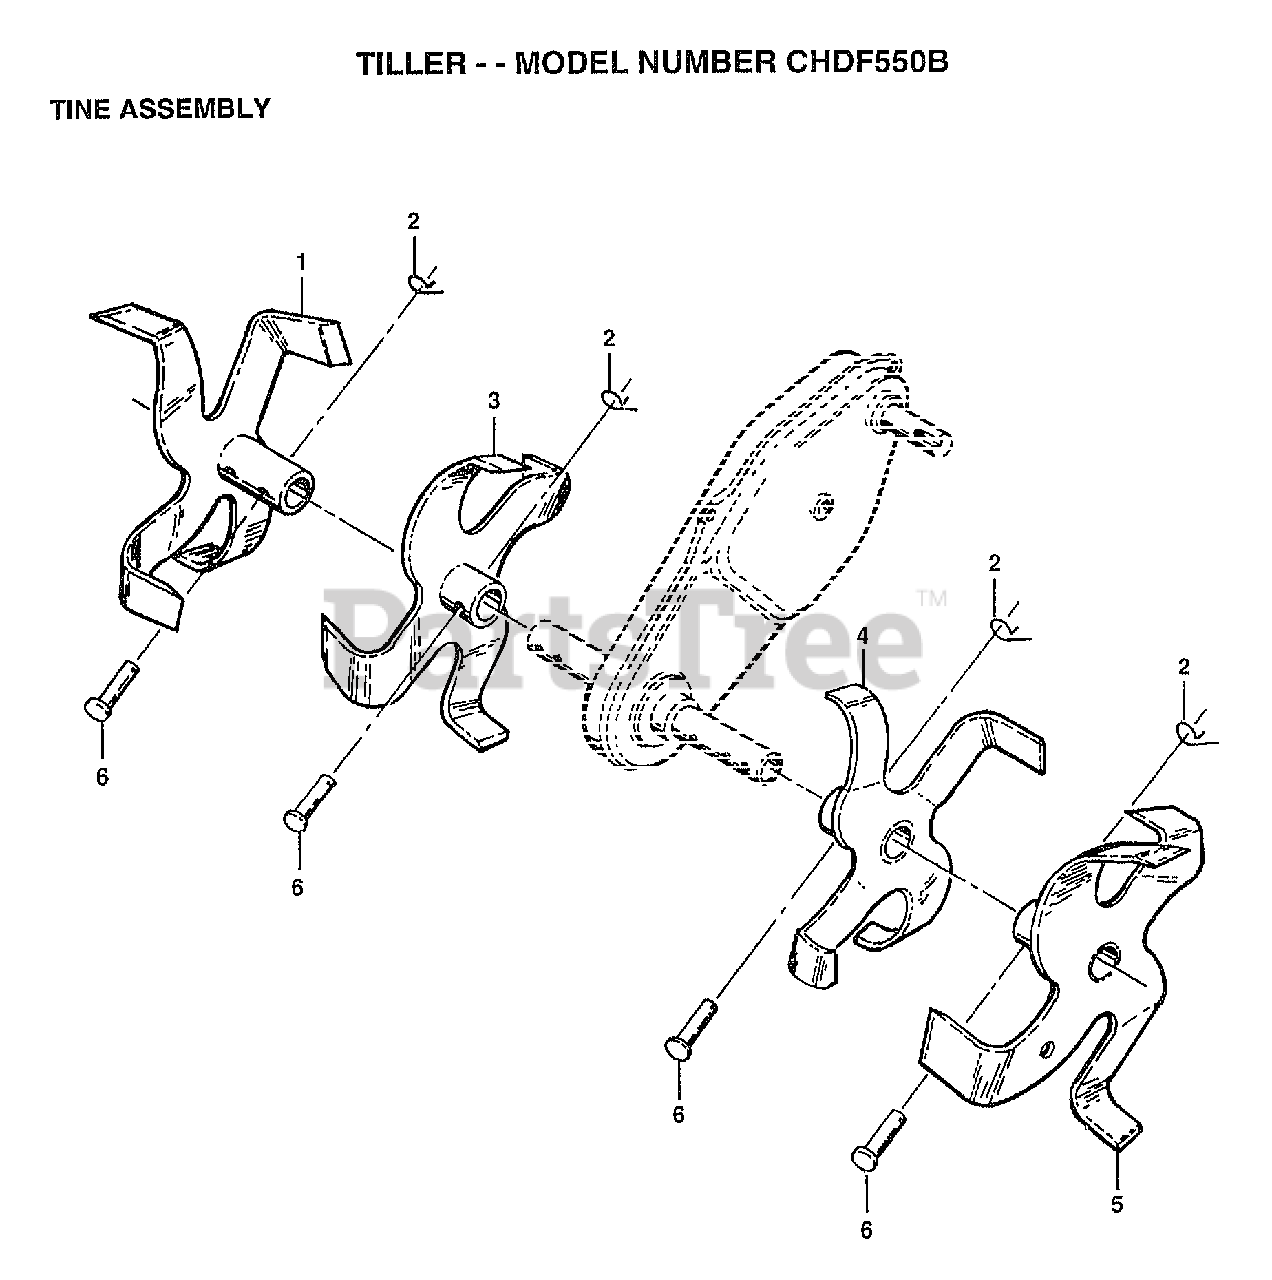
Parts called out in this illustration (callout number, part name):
1	"TINE ASM,OUTER RH"
2	RETAINER.SPRING
3	"TINE ASM.INNER,RH"
4	TINE ASM.INNER LH
5	"TINE ASM,OUTER LH"
6	RIVET.PAN HD.1.75
